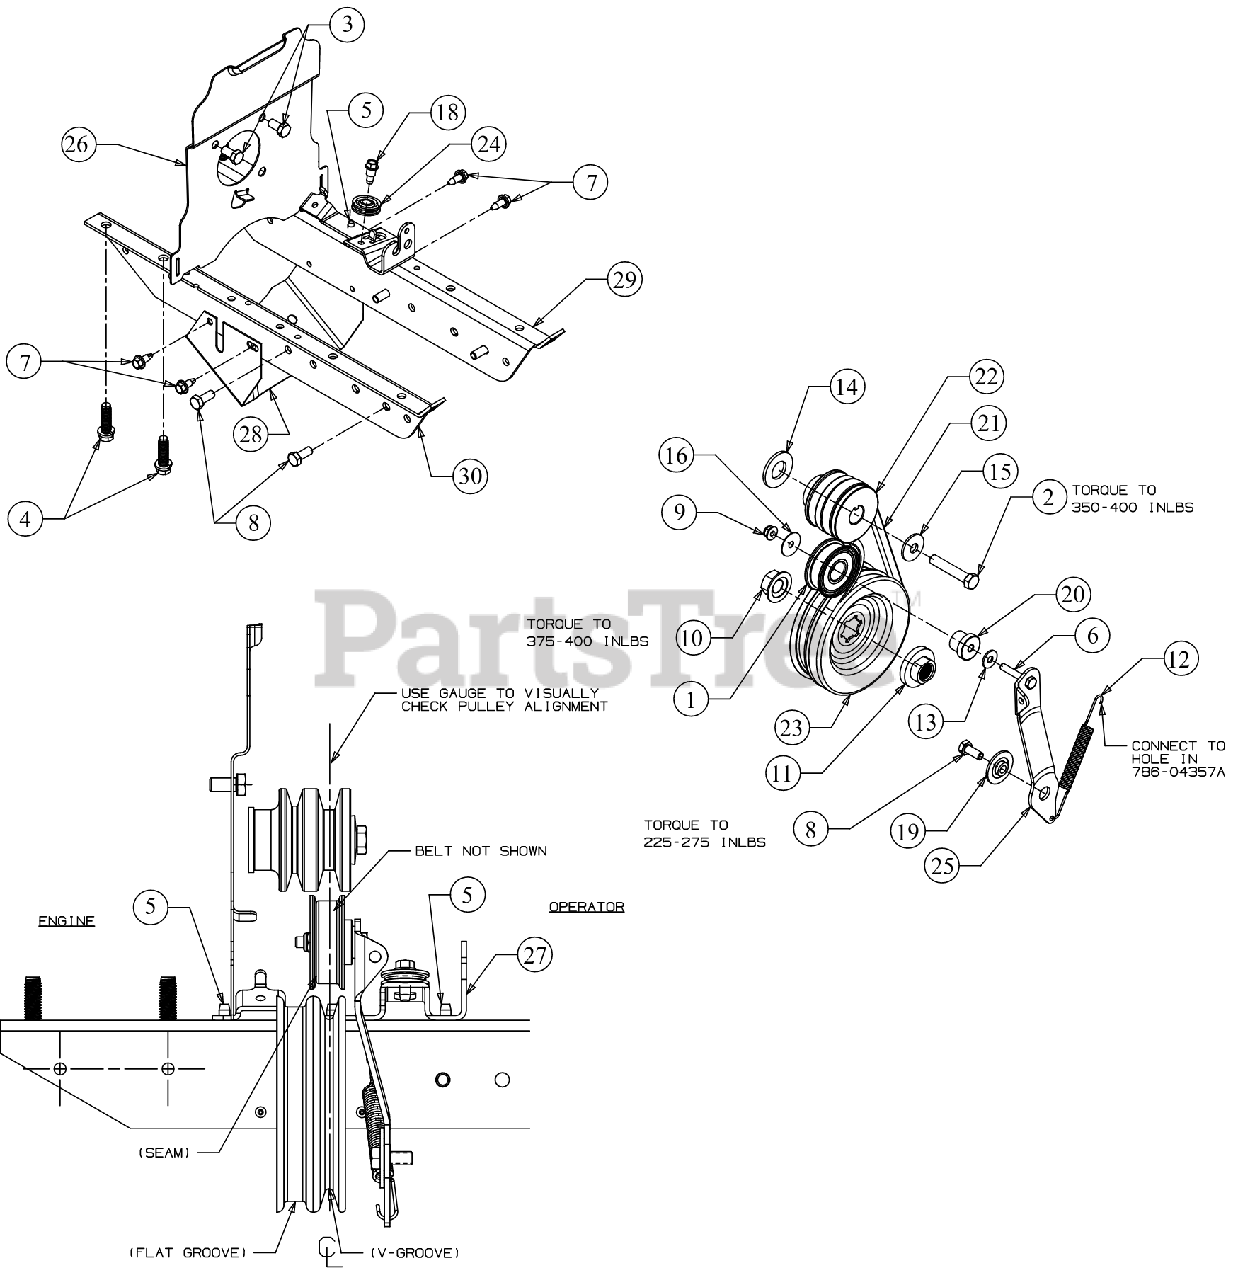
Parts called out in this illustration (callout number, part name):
1	IDLER PULLEY ASSEMBLY
1	BEARING SLEEVE
1	BALL BEARING
2	HEX SCREW 3/8-24 X2.00
3	HEX SCREW 5/16-24 x .62
4	SCREW 3/8-16 x 1.250
5	SCREW 1/4-20 X.500
6	SCREW 1/4-20 x 1.50 GR.5
7	SCREW 1/4-14 x .625
8	SCREW 5/16-18 x .750
9	FLANGE LOCK NUT
10	FLANGE NUT W/HUB
11	PULLEY HUB
12	RETURN SPRING
13	FLAT WASHER .28 ID x .74 OD x .063
14	FLAT WASHER
15	BELL WASHER
16	FLAT WASHER
18	SHOULDER SCREW
19	PIVOT IDLER SPACER
20	SHOULDER SPACER
21	V-BELT FWD DRIVE 4L x 25.375
22	ENGINE PULLEY
23	TRANSMISSION PULLEY
24	CABLE GUIDE ROLLER
25	FORWARD IDLER BRACKET
